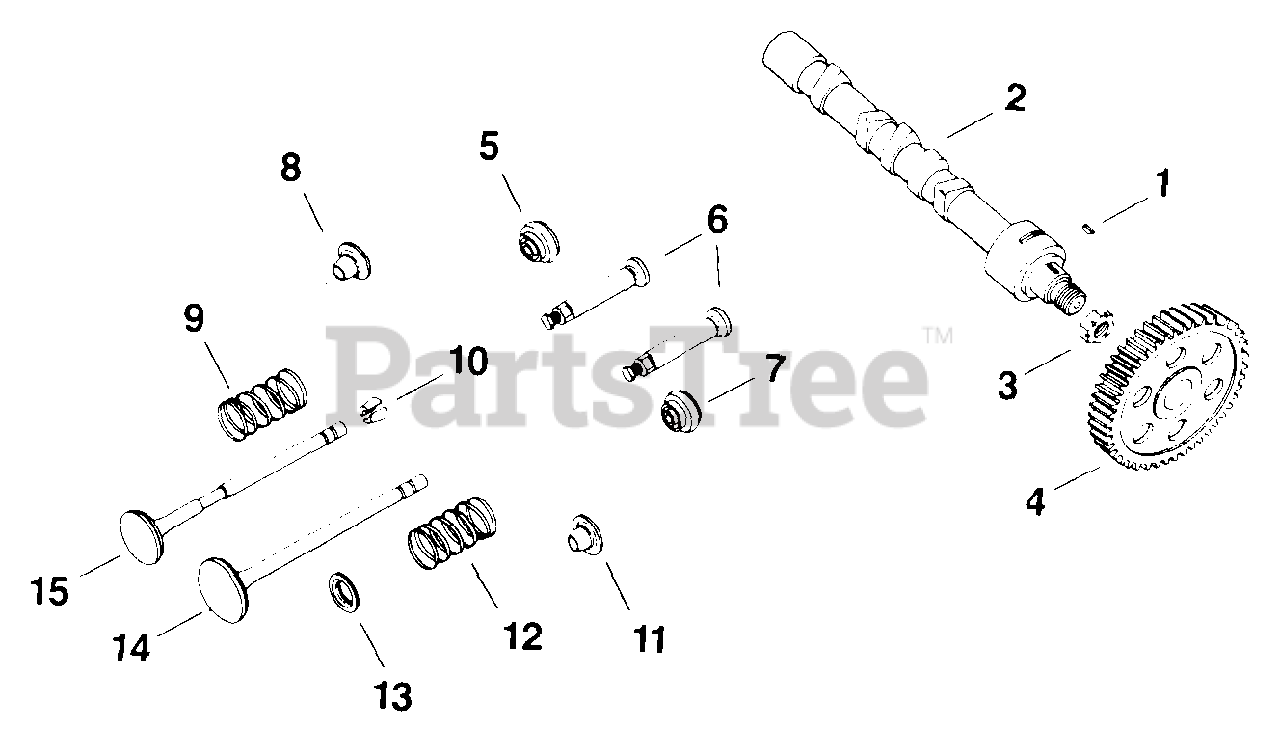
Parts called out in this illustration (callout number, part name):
1	KEY, 1/8" X 1/2"
4	KIT - USE 48 755 34
5	ROTATOR - USE 52 413 01
6	TAPPET - DISCONTINUED
9	SPRING, INTAKE VALVE
10	KIT, RETAINER
11	RETAINER, VALVE SPRING
12	SPRING, EXHAUST VALVE
13	RETAINER, SPRING
14	VALVE, INTAKE
15	VALVE, EXHAUST
